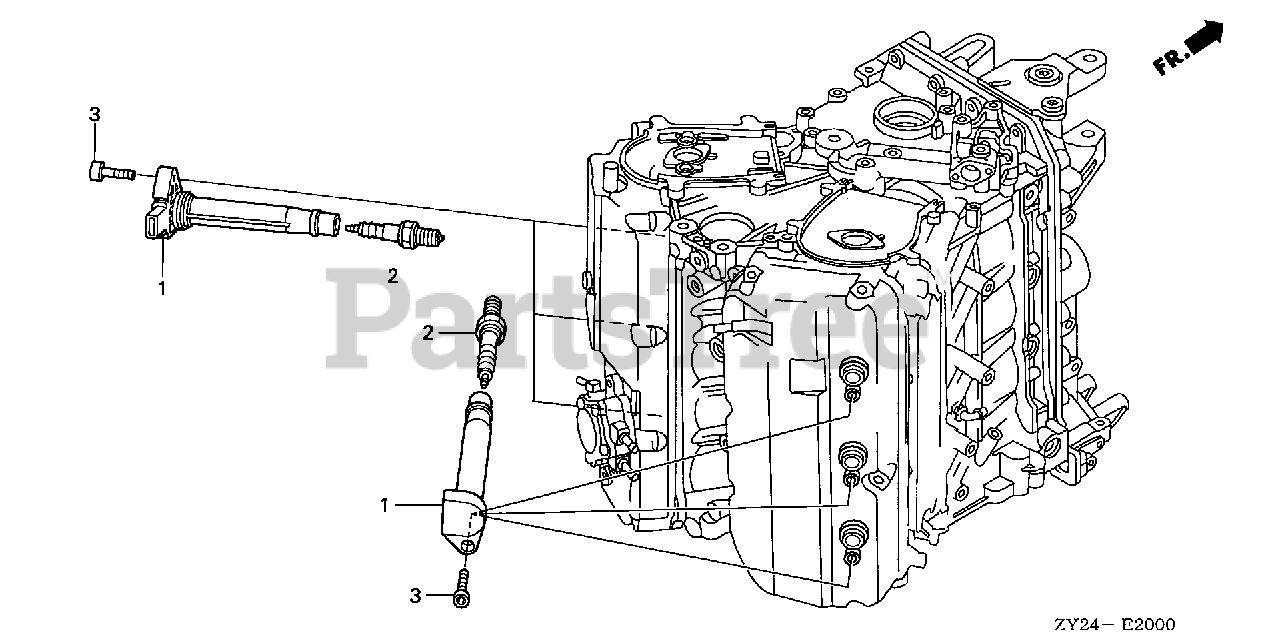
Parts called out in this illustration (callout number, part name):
1	COIL, PLUG HOLE
2	SPARK PLUG (IZFR6F11) (NGK)
2	SPARK PLUG (VKJ20RZ-M11) (DENSO)
3	BOLT, SOCKET (6X25)
